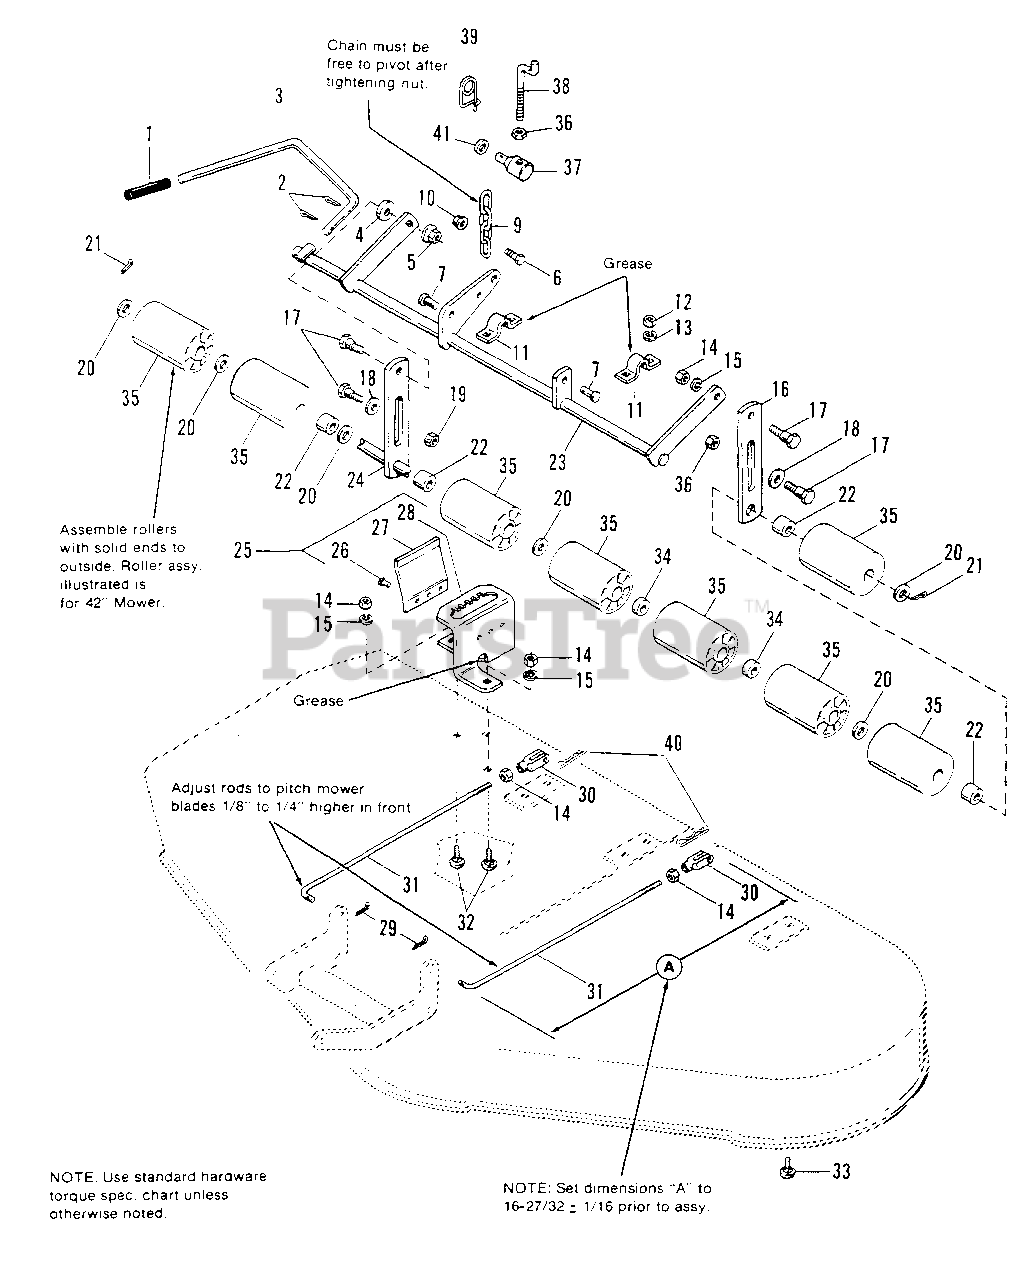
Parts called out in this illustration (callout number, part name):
2	PIN, Cotter, 1/8 x 1
3	LEVER Control
4	WASHER, Plain, 13/32
5	LOCKNUT Hex, Flange, Whiz, 3/8-16
6	CAPSCREW, Hex, 5/16-18 x 1
7	PIN, Clevis
8	ROD, Lift (Incl. Ref. No. 36, 37, 39 & 41)
9	CHAIN, Lift
10	LOCKNUT, Flange, 5/16-18
11	STRAP (Qty. 3 on 48")
12	NUT, Hex, 5/16-18 (Qty. 6 on 48")
13	LOCKWASHER, 5/16 (Qty 6 on 48")
14	NUT, Hex 3/8-16
15	LOCKWASHER, 3/8
16	BAR, Roller
17	BOLT, Shoulder, 3/8-16 X 1.34
18	WASHER, Plain, 1/2
19	NUT Esna, Lock, 3/8-16
20	WASHER, 25/32 x 1-1/4 (Qty. 9 on 48")
21	PIN, Cotter, 3/16 x 1
22	SPACER, .66 ID
23	ARM ASSY., Mower (42" only)
23	ARM ASSY., Mower (48" only)
24	SHAFT ASSY., Roller (42" only)
24	SHAFT ASSY., Roller (48" only)
25	QUADRANT ASSY. (Incl. Ref. Nos. 26, 27 & 28)
29	PIN, Cotter, 3/32 x 3/4
30	CLEVIS, Adj.
32	BOLT, Carriage, 3/8-16 x 3/4
33	BOLT, Carriage, 5/16-18 x 3/4 (Qty. 6 on 48")
34	SPACER (Used on 42" only)
35	ROLLERS (Qty. 10 on 48")
36	NUT, Jam 5/16-18
38	ROD, Lift (Short)
39	CLIP, Pin, Safety
40	CLIP, Hair Pin
